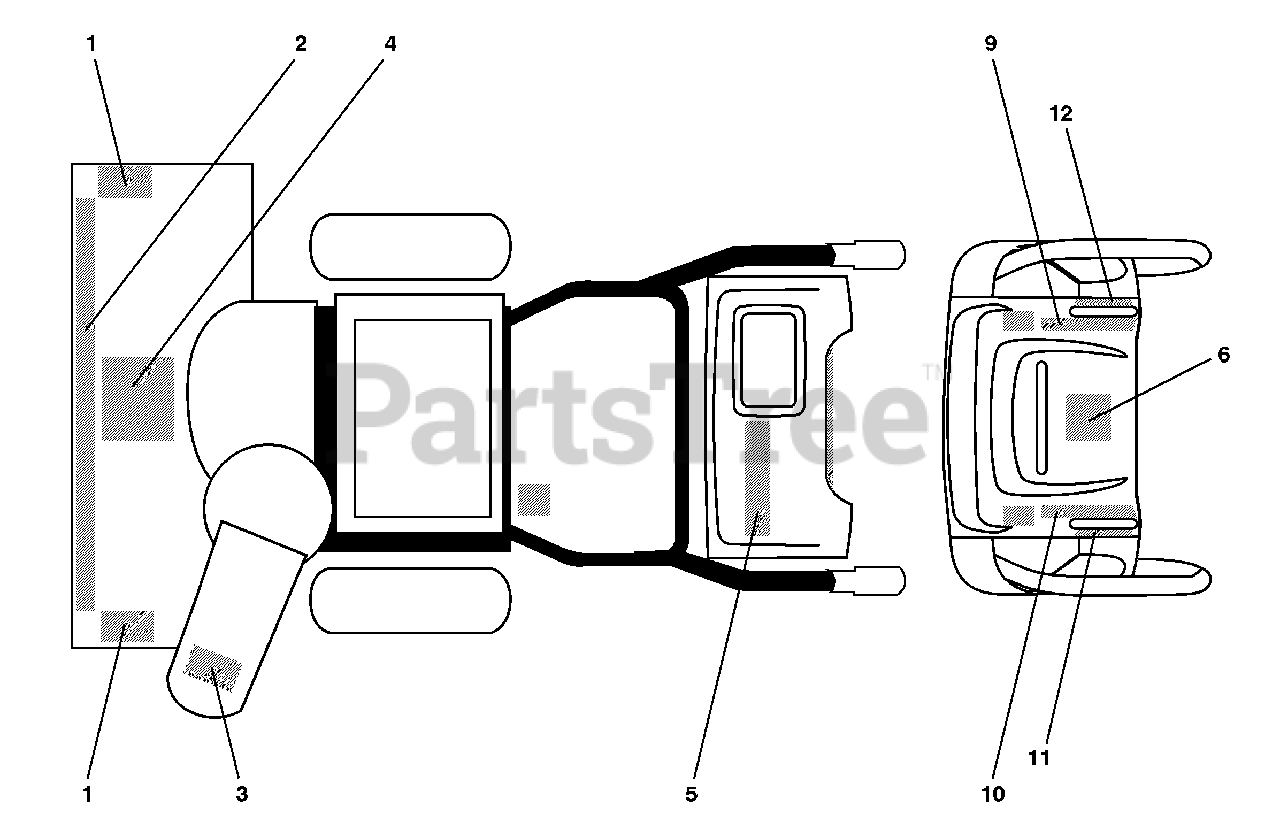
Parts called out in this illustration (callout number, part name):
1	DECAL, DANGER
2	DECAL, HUSQ
3	DECAL, DANGER, DEFLECTOR
4	DECAL, DANGER
5	DECAL, HUSQ
6	DECAL, INSTRUCTION
9	DECAL, SPEED CONTROL
10	DECAL, REMOTE DEFLECTOR
11	DECAL, LH TRIGGER
12	DECAL, RH TRIGGER
12	OWNER’S MANUAL, ENGLISH
12	OWNER’S MANUAL, FRENCH
